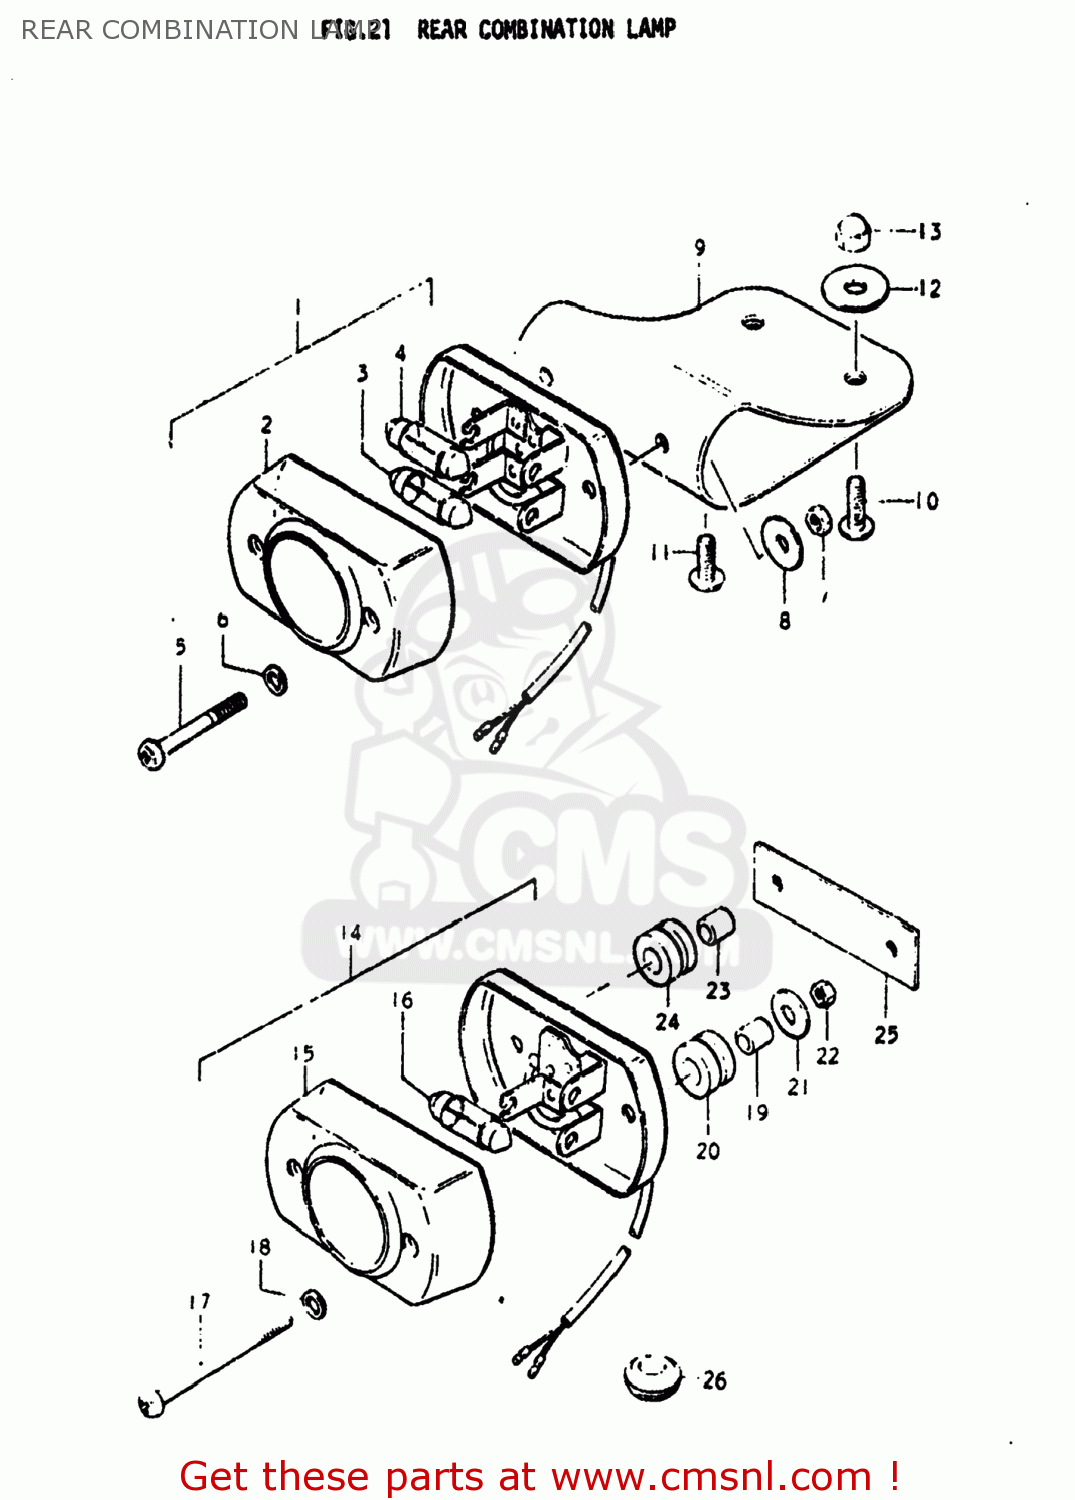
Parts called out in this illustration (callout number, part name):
1	LAMP ASSEMBLY,REAR COMBINATION
2	LENS,REAR COMBINATION LAMP
3	BULB
4	BULB
5	SCREW,REAR COMBINATION LAMP LENS
6	WASHER,REAR COMBINATION LAMP
7	NUT
8	WASHER(5.2X16X1)
9	CUSHION,REAR COMBINATION LAMP
10	SCREW
11	SCREW 6X12
12	WASHER (6.5X20X1.2)
13	NUT
14	LAMP ASSEMBLY,TAIL
15	LENS,REAR COMBINATION LAMP
16	BULB
17	SCREW,REAR COMBINATION LAMP LENS
18	WASHER,REAR COMBINATION LAMP
19	BUSHING
20	CUSHION
21	WASHER(5.2X16X1)
22	NUT
23	BUSHING
24	CUSHION
26	GROMMET
